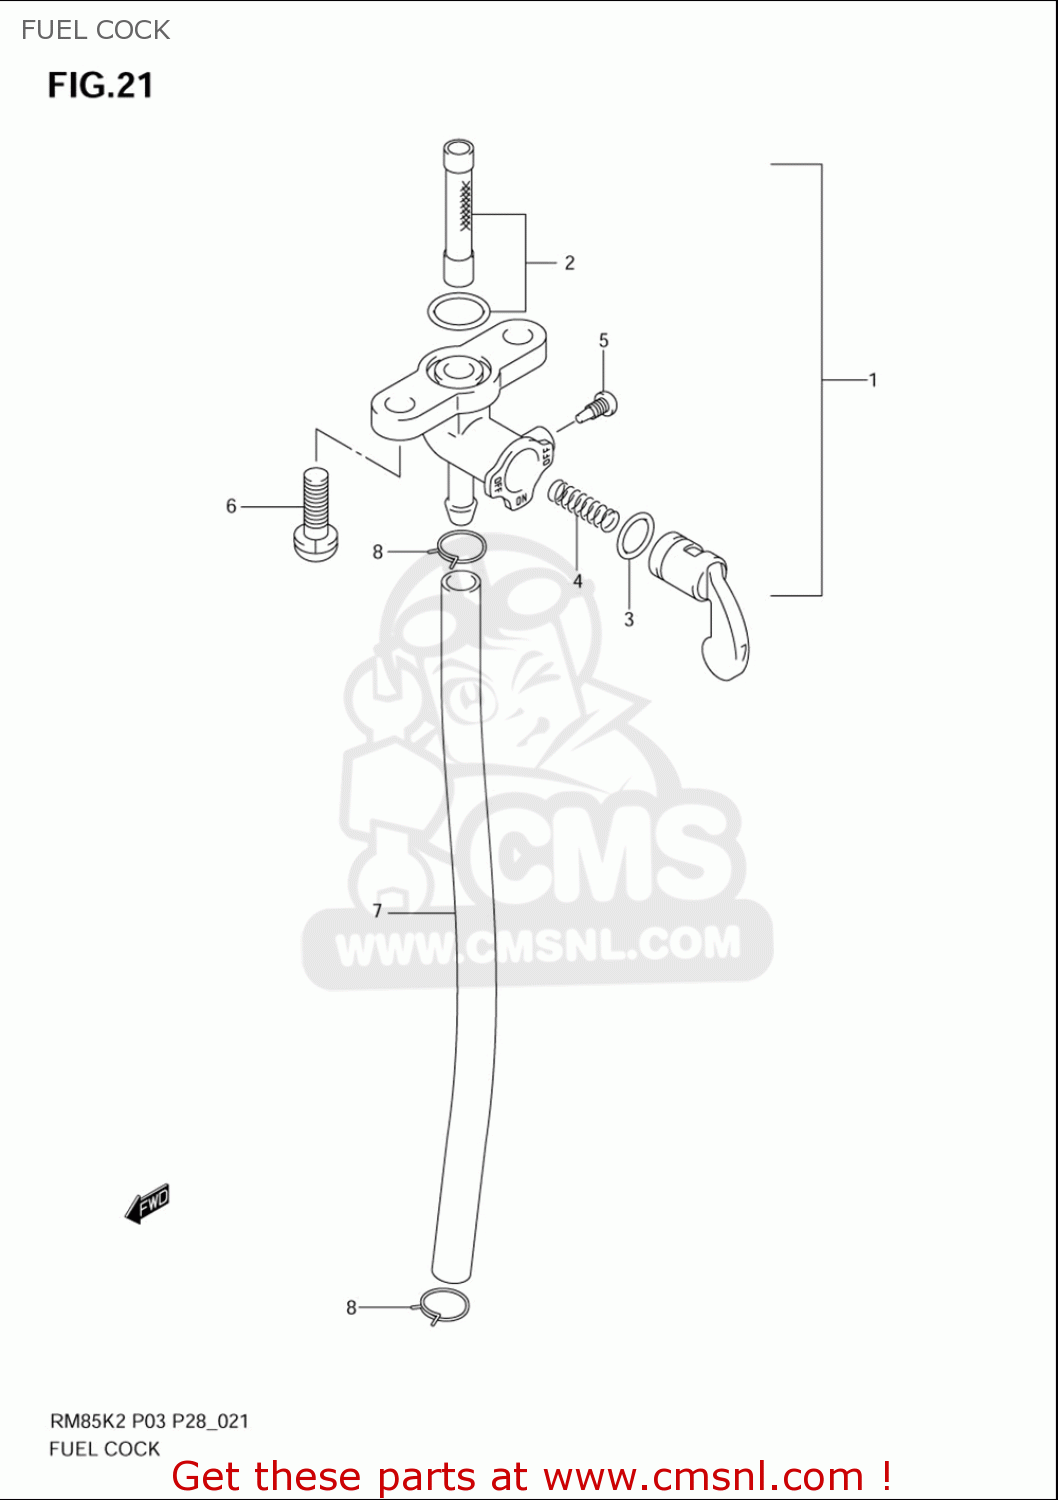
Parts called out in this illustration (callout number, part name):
1	COCK ASSY,FUEL
2	FILTER SET FUEL
3	O RING,LEVER
4	SPRING
5	SCREW
6	SCREW
7	HOSE(5X8.2X600)
8	CLIP
